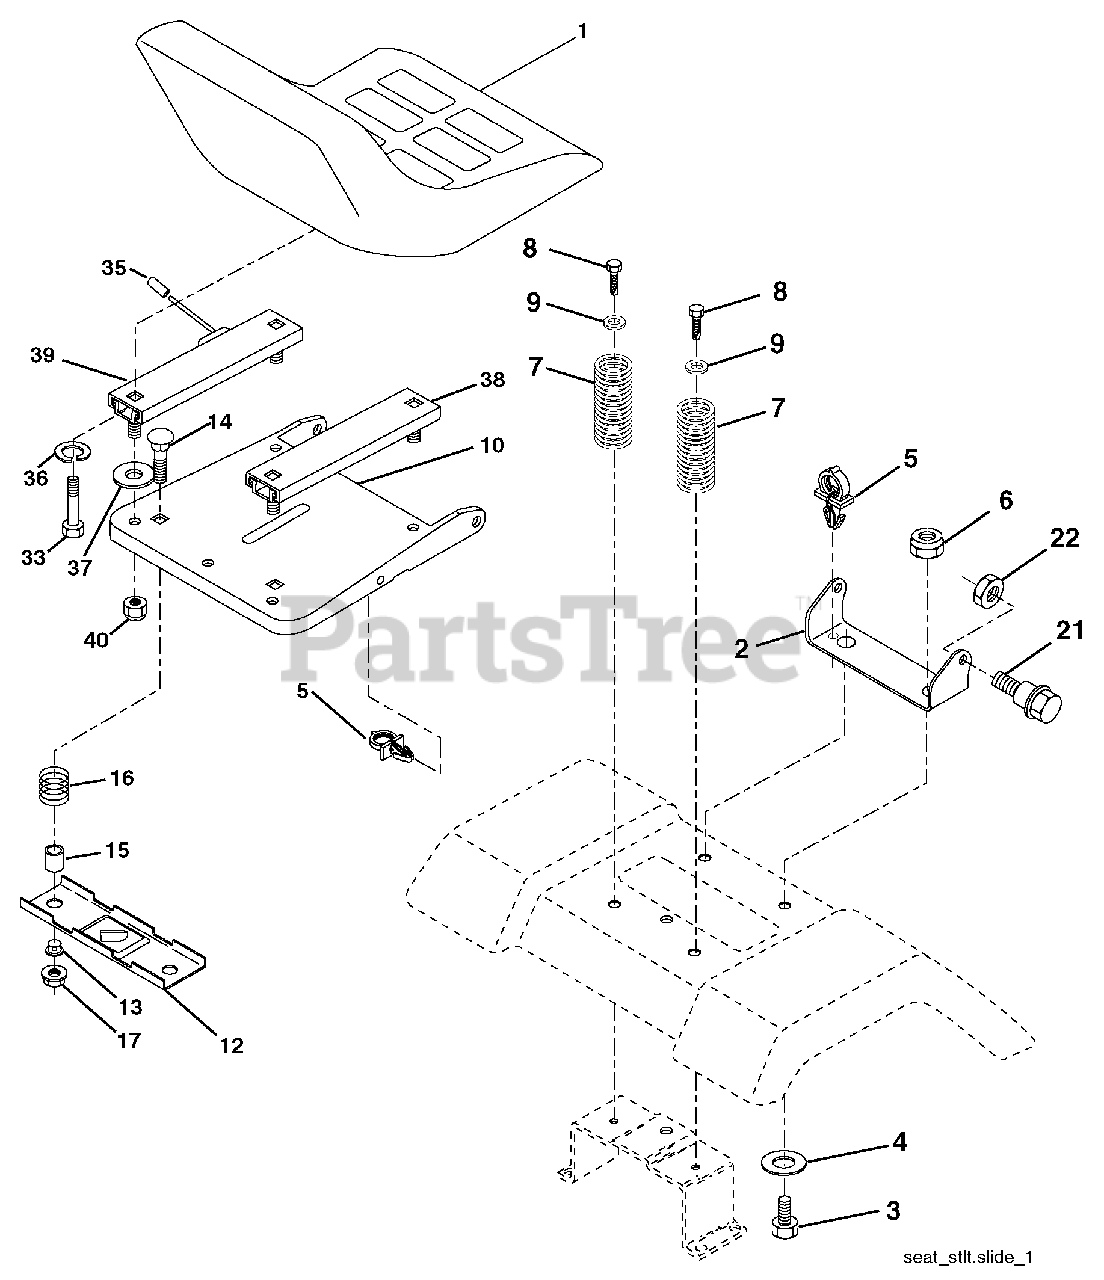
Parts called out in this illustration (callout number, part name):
1	Seat
2	Bracket Seat Pivot
3	Bolt Hex 3/8-16 x 1
4	Washer 13/32 x 1 x10 Ga.
5	Clip Push-In Hinged
6	Nut Lock Hex w/Ins 3/8 - 16
7	Spring Seat Cprsn 2 250 Blk Zi
8	Screw 3/8-16 x 1.5
9	Washer 13/32 x 1 x 14 Ga.
10	Pan Asm. Seat
11	Knob Seat
12	Bracket Pnt Mounting Switch
13	Bushing Snap Blk Nyl
14	Bolt Rdhd Sht Nk 1/4 - 20 x 1 -1/2
15	Spacer Split .28 x .96
16	Spring Cprsn
17	Nut Lock 1/4 Lge Flg
21	Bolt Shoulder 5/16-18 unc-2A
22	Nut Lock Hex w/Ins 5/16 - 18
24	Washer 17/32 x 1-3/16 x 12 Ga.
25	Bolt Shoulder 5/16-18 x .62
